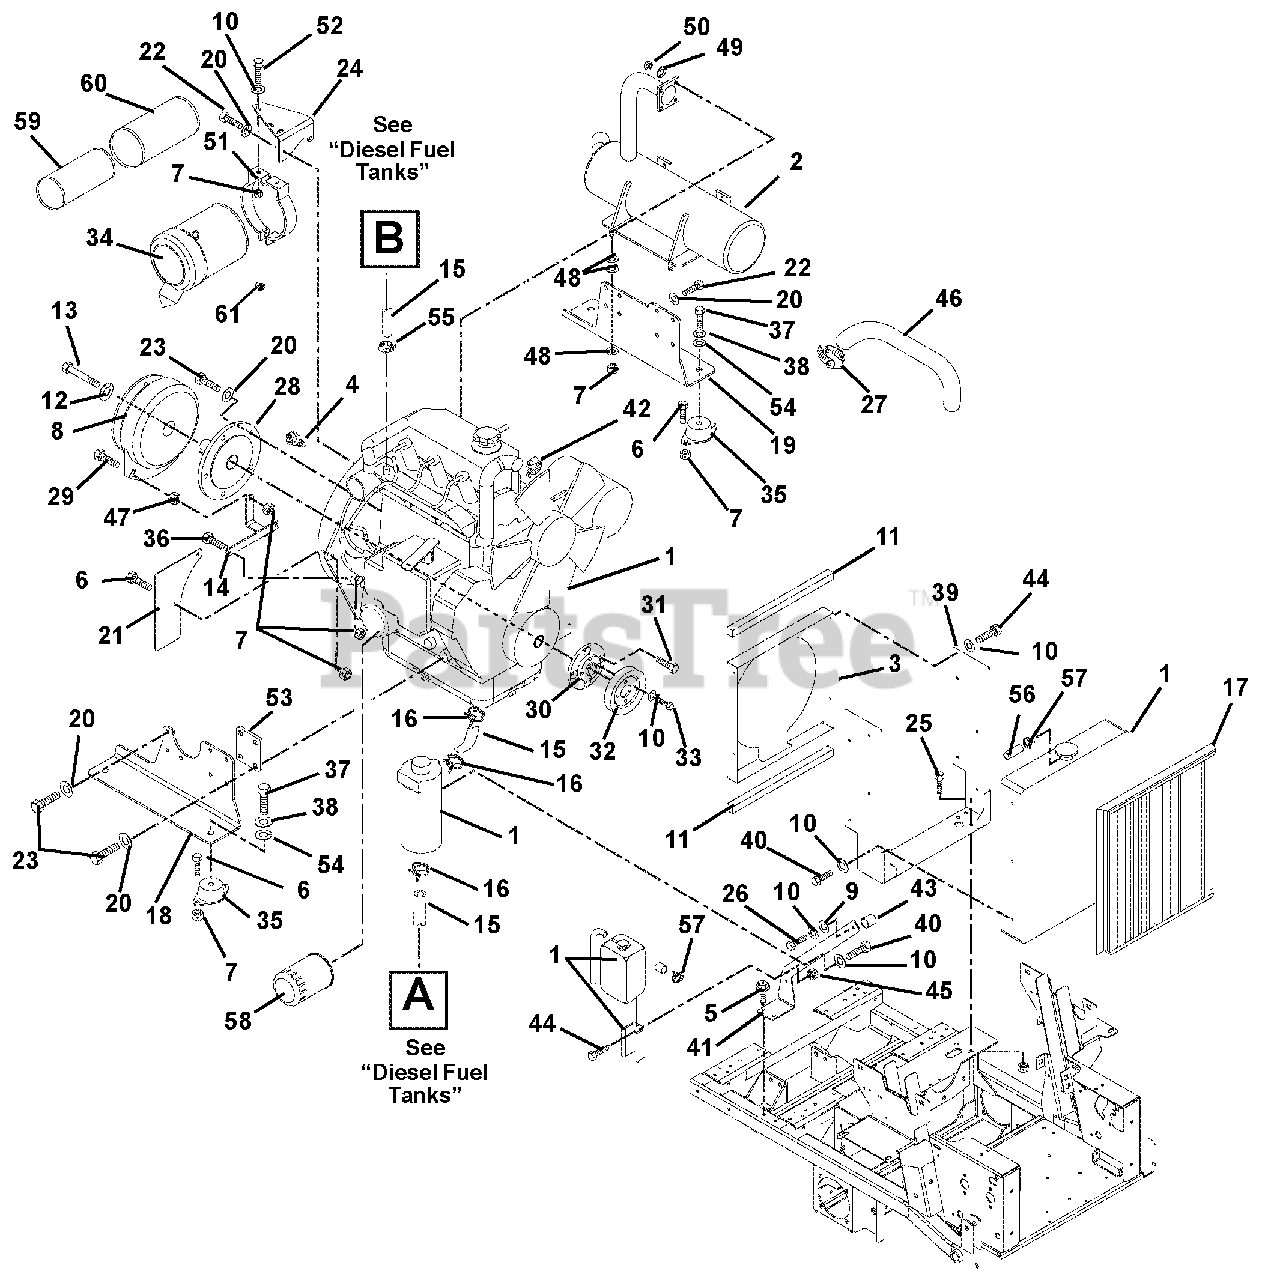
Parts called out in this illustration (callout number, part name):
1	Engine, 27HP Diesel (Daihatsu) (316, 322)
2	Muffler (316, 322)
3	Weldment, Radiator Shroud
4	Sender, Temperature
5	Screw, Tapping .38-16 x .75 Hex Washer Head
6	Bolt, Hex .31-18 x .75 Grade 5
7	Nut, Locking Top Flange .31-18
8	Clutch, Electric with HI Temp Grease
9	Washer, Flat Steel .281 x .62 x .065
10	Washer, Locking .25 x .062 Regular
11	Seal, Trim-LOK Bulk .06 Bubble
12	Washer, Locking .44 x .109
13	Bolt, Hex .44-20 x 2.50 Grade 5
14	Stabilizer, Clutch
15	Gas Line, Bulk .31" ID
16	Hose, Clamp
17	Screen, Radiator
18	Mount, Engine Right Hand
19	Mount, Engine Left Hand
20	Washer, Lock .31 x .078 Regular
21	Guard, Flywheel
22	Bolt, Hex M8-1.25 x 20
23	Bolt, Hex M8 x 1.25 x 25 Grade 8
24	Bracket, Air Cleaner
25	Bolt, Hex .38-16 x 1.00 Grade 5
26	Bolt, Hex M6-1.00 x 45
27	Clamp, 2.50" Dia. Hose
28	Weldment, Stub Shaft
29	Bolt, Hex .31-18 x 1.50 Grade 5
30	Adapter, Sheave
31	Bolt, M8-1.25 x 25
32	Sheave, Poly-V 1.0 x 3.25
33	Bolt, Hex .25-20 x .75 Grade 5
34	Assembly, Air Cleaner
35	Mount, Engine
36	Bolt, Hex .31-18 x 1.00 Grade 5
37	Bolt, Hex .50-20 x 1.00 Grade 5
38	Washer, Locking .50 x .125 Regular
39	Bracket, Radiator Mounting
40	Bolt, Hex M6-1 x 16
41	Bracket, Overflow Mounting
42	Clamp, Hose 1.50 x .81 x 1.42
43	Spacer .328 x .76 x 1.01
44	Bolt, Hex .25-20 x .75 Grade 5
45	Nut, Locking Top Flange .25-20
46	Hose, Air Cleaner (316, 322)
47	Nut, Hex .31-18
48	Washer, Flat Steel .38 x .875 x .083
49	Washer, Locking .31 x .078 Regular
50	Nut, Hex M8-1.25
51	Bracket, Air Cleaner Mount
52	Washer, Flat Steel .38 x .875 x .083
53	Spacer, Engine Mounting
54	Washer, Flat Steel .531 x 1.06 x .095
55	Hose Clamp
56	Gas Line, Bulk .25 I.D.
57	Clamp, Hose Wire .49/.51 x .116
58	Oil Filter
59	Element, Inner Safety
60	Element, Outer Primary
61	Plug, Pipe .125-27
NS	Kit, Break Pole Module Replacement‘
